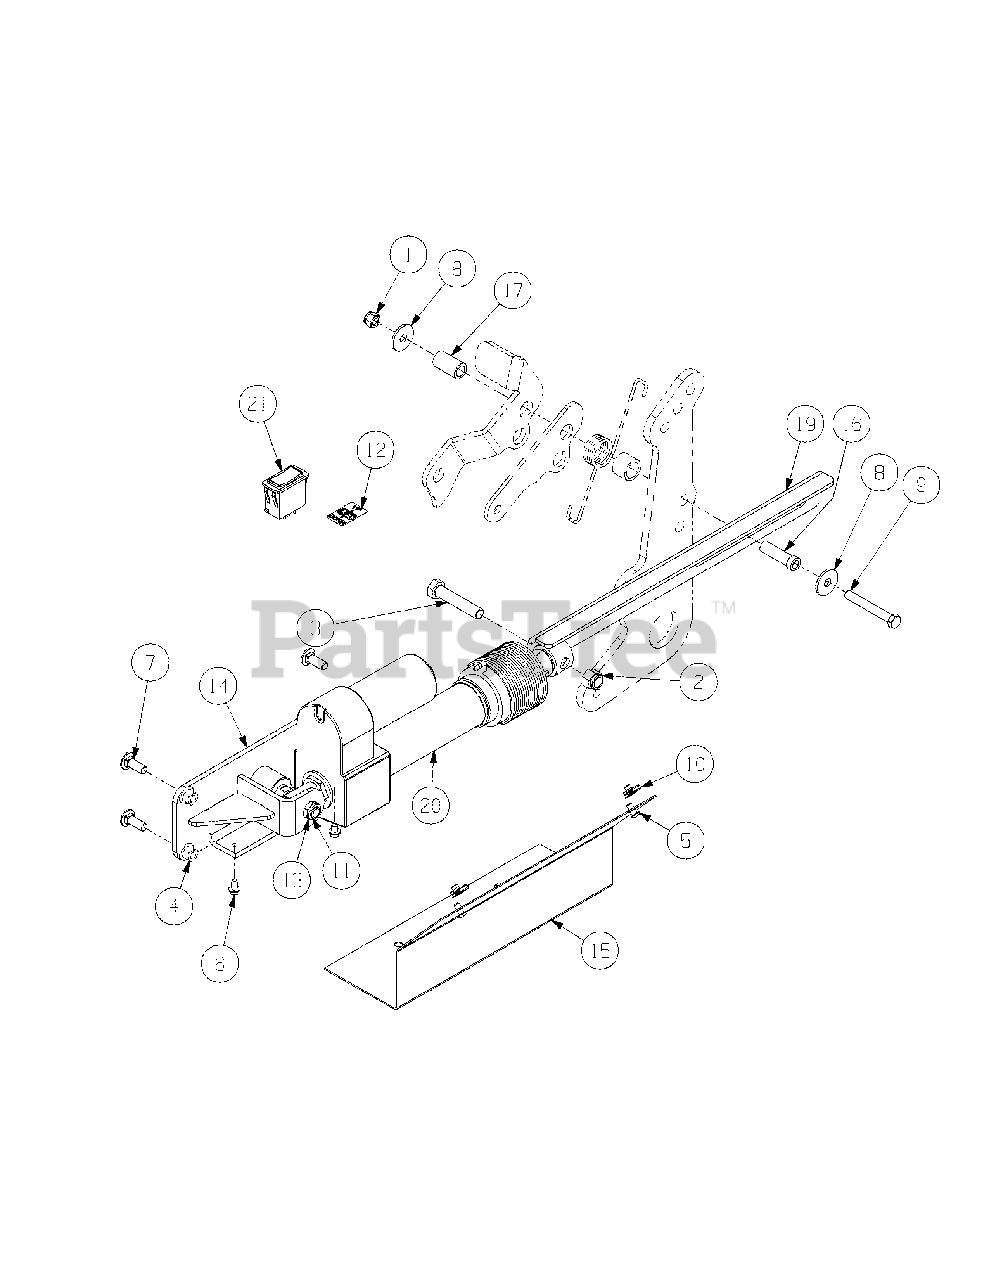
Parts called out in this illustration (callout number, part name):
1	Nut, 3/8-16, Nylock
2	Nut, 1/2-13, nylock
3	HHCS, 1/2-20 x 2.50
4	Nut, 3/8-16, Flangelock
5	Capscrew, 1/4-20 x .500
6	Self Tapping Screw, 1/4-20 x .50
7	Carriage Bolt, 3/8-16 x 1.00
8	Washer, 1.25 x .411 x .100
9	HHCS, 3/8-16 x 2.75
10	U-Nut, 1/4-20
11	Pivot Pin
12	Label, Up/Down
13	Jam Nut, 1/2-13
17	Spacer, .515 ID x .75 OD x 1.313
